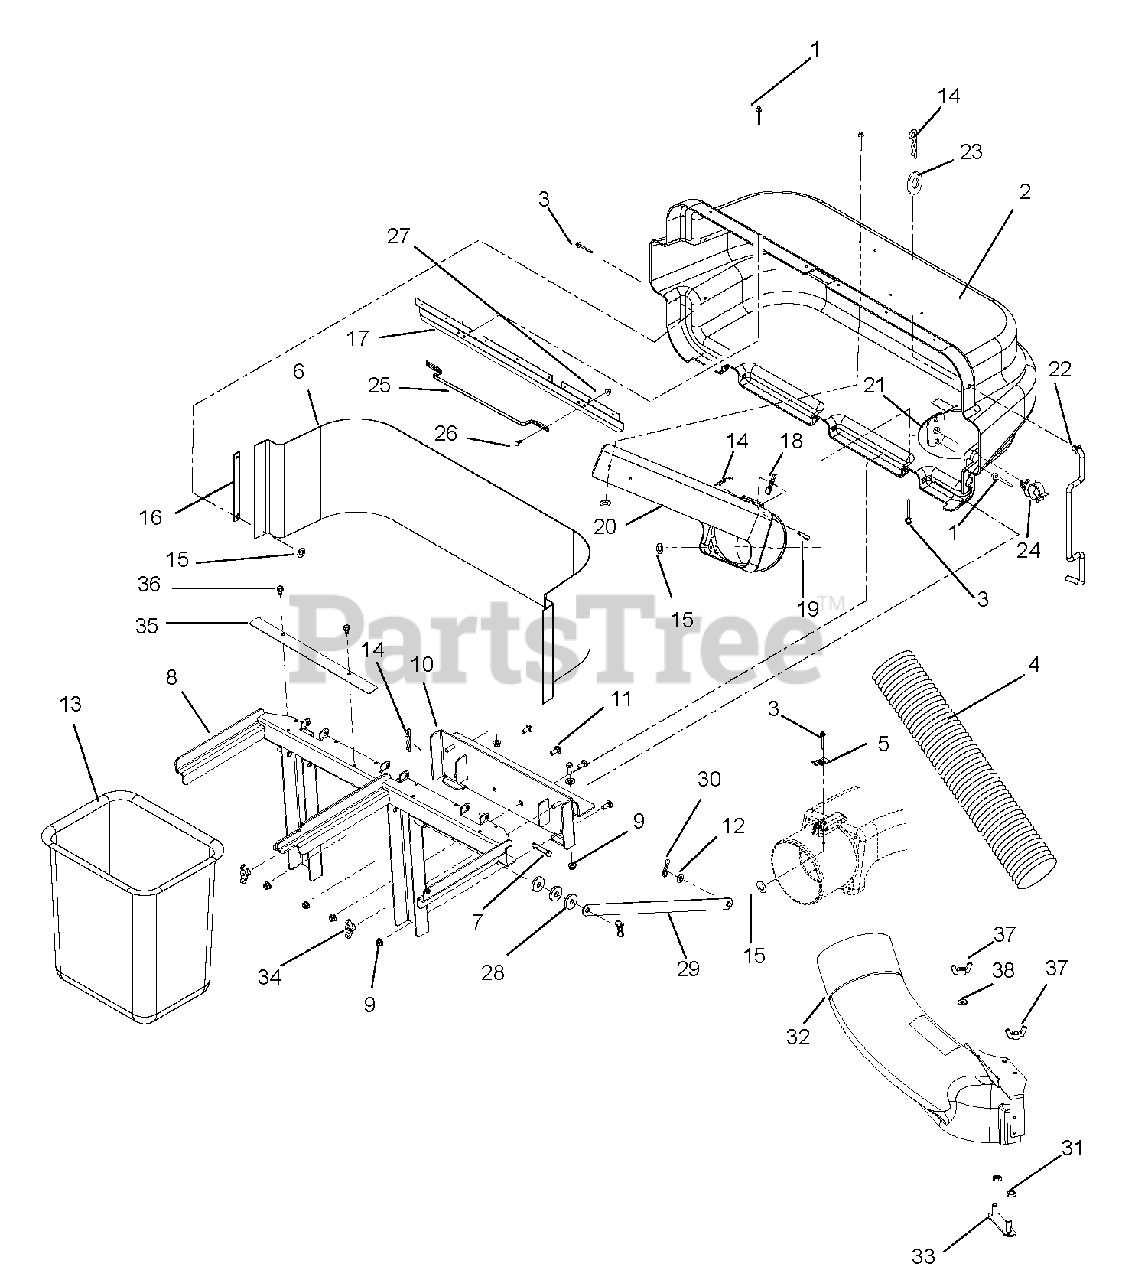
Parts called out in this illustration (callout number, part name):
1	Rivet, Pop .187 x .402
2	Cover, Bagger with Decal
3	Rivet, Pop .187 x .375
4	Hose 7 x 45
5	Thumb Latch
6	Screen, Bagger
7	Pin, Clevis .368/.373 x 3.25
8	Weldment, Bagger Frame
9	Nut, Locking Nylon Flange
10	Weldment, Mounting Plate
11	Bolt, Round Head Square Neck .38-16 x 1.00
12	Washer, Flat Steel .438 x 1.00 x .083
13	Bag, Mesh
14	Pin, Hair
15	Washer, Flat Steel .219 x .50 x .049
16	Strap, Cover
17	Latch, Cover
18	Indicator, Flow
19	Pin, Clevis .31 x 2.62 Grade 5
20	Boot, Upper
21	Plate, Rod Clip
22	Prop, Rod, Bagger
23	Washer, Flat Steel .046 x .812 x .065
24	Clip .38
25	Handle, Bagger
26	Bolt, Round Head Square Neck .25-20 x .75 Grade 5
27	Nut, Locking Top Flange .25-20
28	Washer, Flat .515 x 1.62 x .250
29	Pin, Bow Tie Locking Cotter .091 x 1.875
30	Weldment Strap, Bagger
31	Nut, Locking-Center-Jam .31-18
32	Bagger Boot Assembly
33	Weldment, Boot Mount Strap
34	Nut, Wing .375-16
35	Bracket, Bagger Overlap
36	Screw, Tapping .31-18 x .50 Hex Washer Head Thread Rolling
37	Nut, Nylock Wing .312-18
38	Washer, Flat-Steel .406 x .812 x .065
